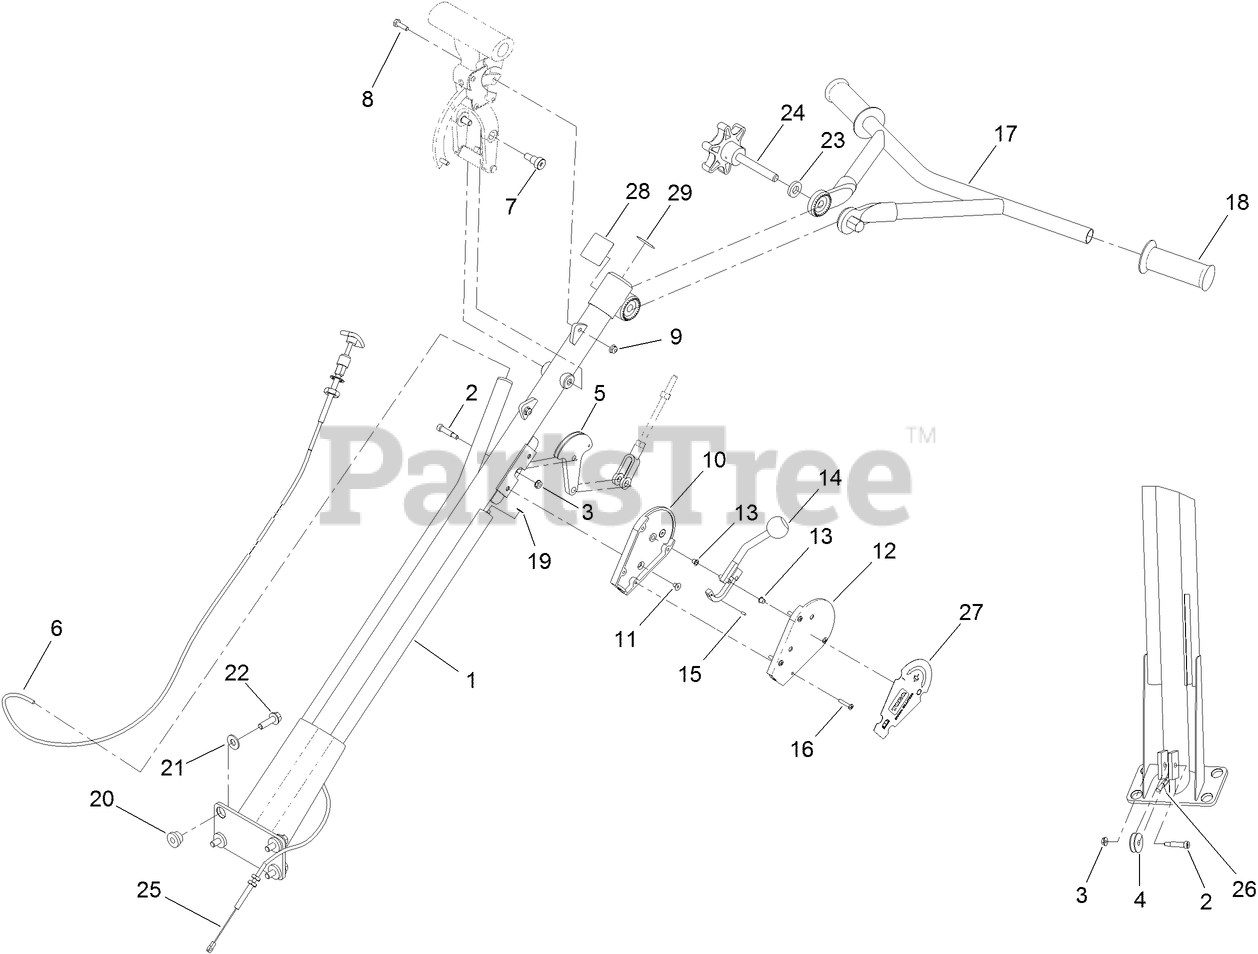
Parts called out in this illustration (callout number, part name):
1	HANDLE-COLUMN, MAIN
2	SCREW-HSBH
3	NUT-KEPS
4	PULLEY-PIVOT
5	CAM-CABLE, TILT PIVOT
6	CABLE-THROTTLE, PUSH/PULL
7	SCREW-HSBH
8	SCREW-HH
9	NUT-HF
10	HOUSING-CLUTCH
11	SCREW
12	COVER-CLUTCH
13	BUSHING-FLANGE
14	LEVER ASM
16	SCREW-PPH
17	HANDLE-ADJUSTABLE
18	GRIP-HANDLE
19	RING-EXTERNAL
20	MOUNT-SHOCK
21	WASHER-FLAT
22	SCREW-HHF
23	WASHER-FLAT
24	KNOB-ADJUSTMENT
25	CABLE-CLUTCH
26	CABLE-TILT
28	DECAL-RAISE, LOWER
29	DECAL-PRO PITCH
